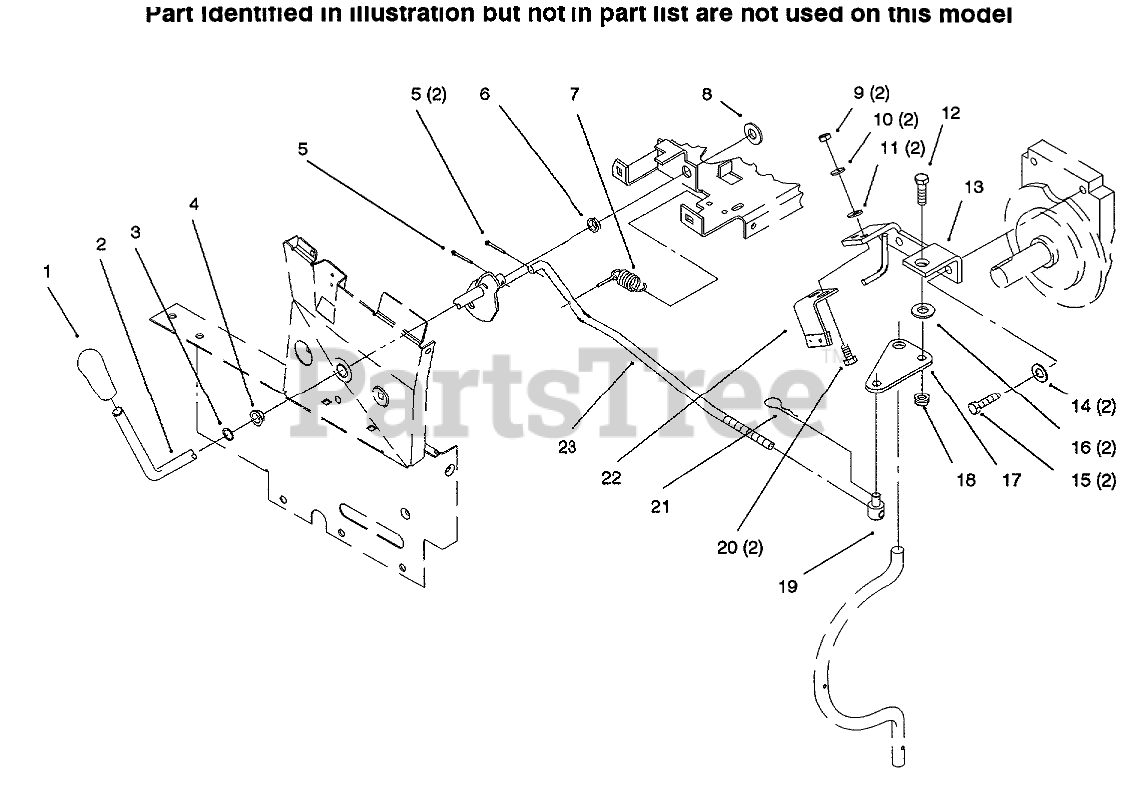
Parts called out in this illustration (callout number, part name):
2	PTO CLUTCH LEVER ASM
3	RING-EXT GRIP
4	BUSHING-NYLINER
5	PIN-COTTER
6	NYLINER BUSHING
7	SPRING
8	SHIM-WASHER
9	NUT-JAM
10	WASHER-LOCK
11	WASHER-FLAT
12	SCREW-HH
13	Bracket-Engine
14	WASHER-LOCK
15	SCREW-HH
16	SPACER-LIFT LINK
17	PLATE
18	NUT-LOCK, NI
19	TRUNNION
20	SCREW-CARR
21	PIN-HAIR
22	ASM-Bracket
22	BRAKE ASM
23	ROD-PTO CLUTCH
